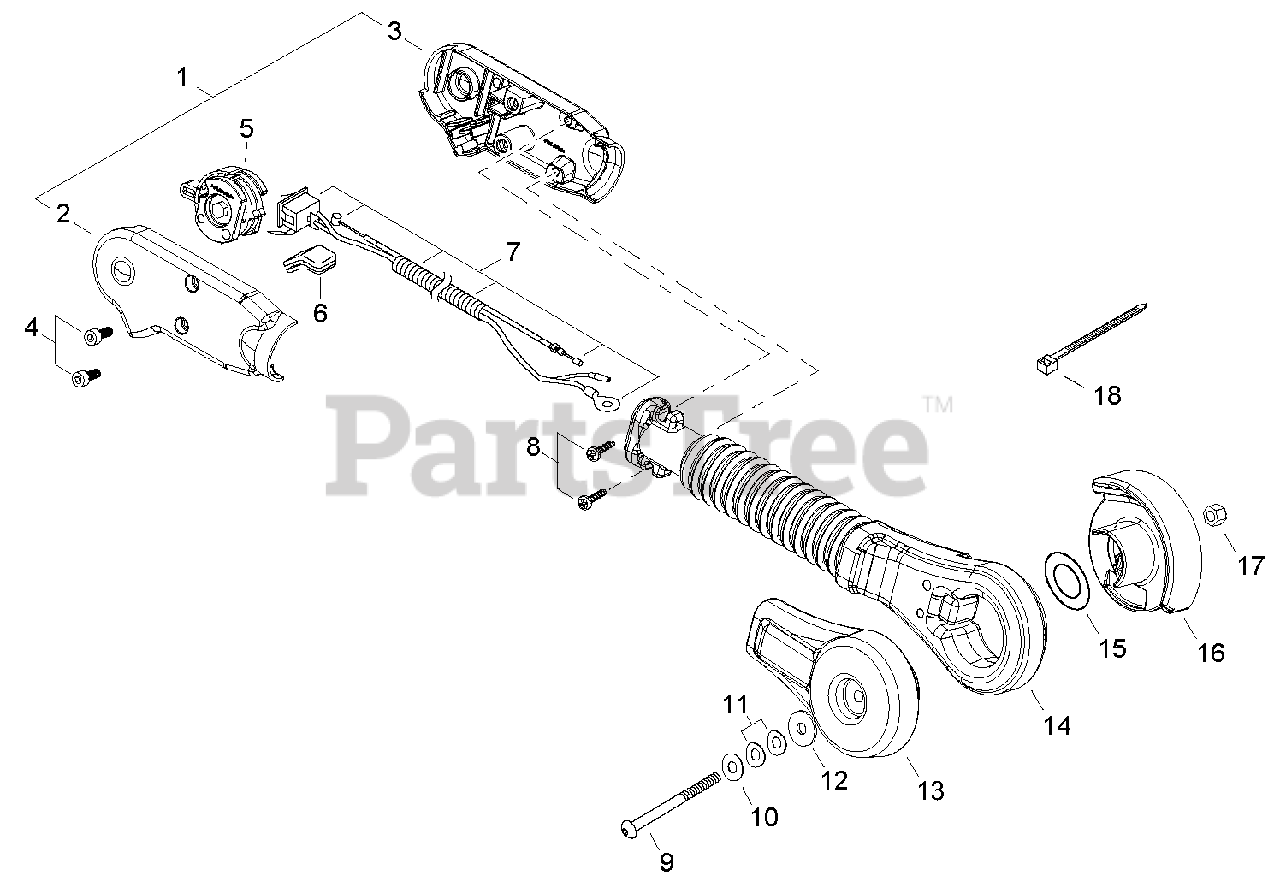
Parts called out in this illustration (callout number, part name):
1	CONTROL HANDLE KIT
2	HANDLE, CONTROL - LEFT
3	HANDLE, CONTROL - RIGHT
4	SCREW - 5X20
5	THROTTLE CONTROL ASSY
7	CONTROL CABLE ASSY
8	SCREW - 5X16
9	SCREW - 6X75
10	WASHER - 6
11	WASHER - SPRING
12	WASHER - 6
13	BRACKET, ARM - OUTER
14	ARM, THROTTLE CONTROL
16	BRACKET, ARM - INNER
17	LOCKNUT - 6
18	TIE, CABLE - SMALL
